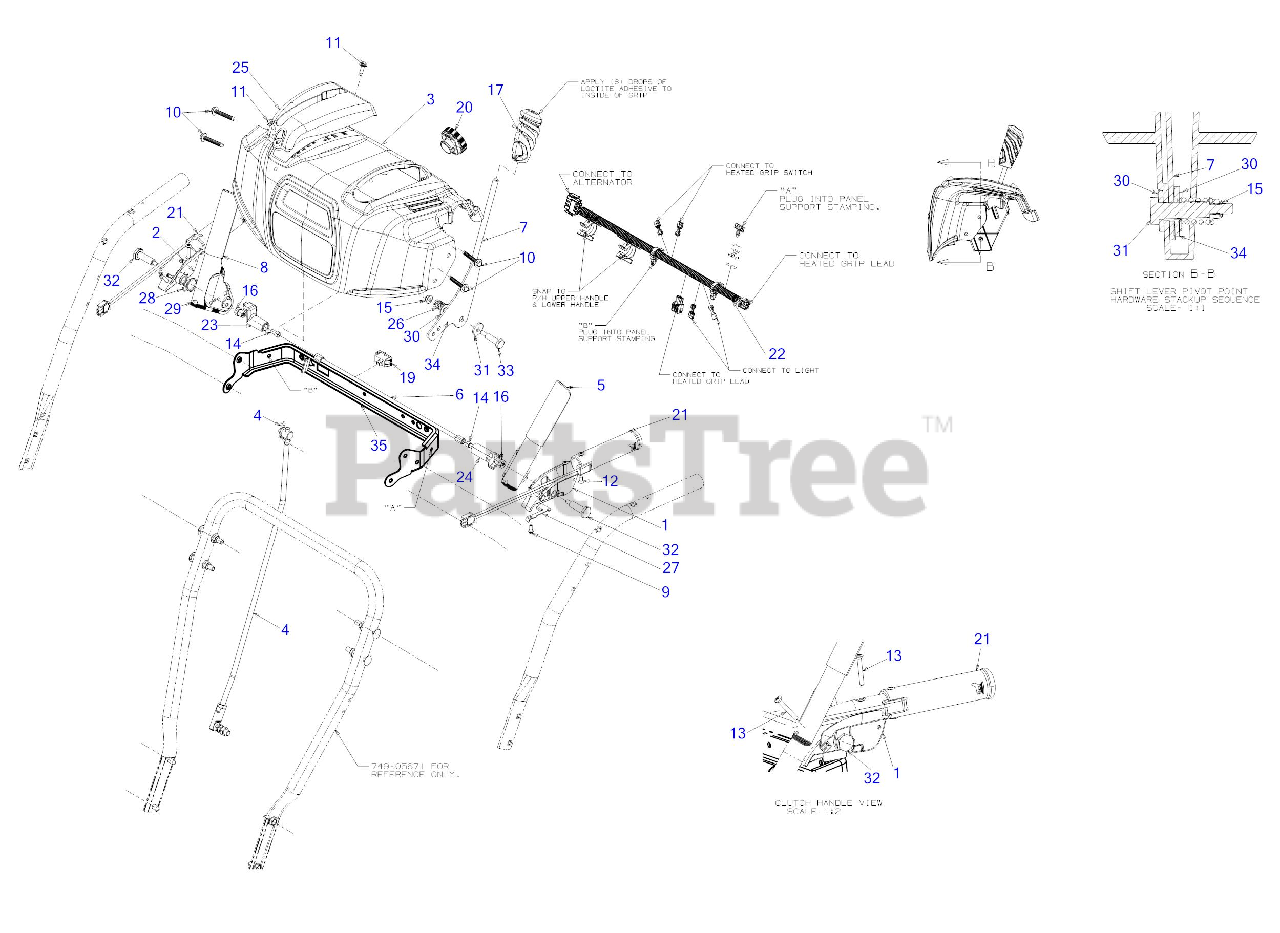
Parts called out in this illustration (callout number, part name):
1	CLUTCH LOCK HANDLE ASSEMBLY (LH)
2	CLUTCH LOCK HANDLE ASSEMBLY (RH)
3	HANDLE PANEL ASSEMBLY
4	SHIFT ROD ASSEMBLY
5	HANDLE ASSEMBLY (LH)
8	HANDLE ASSEMBLY (RH)
9	SCREW #8-16 x .50
10	SCREW 1/4-20 x 1.625
11	SCREW 1/4-10 x .750
12	SCREW #10-16 x .625
13	SCREW #10-24 x 1.375
14	SCREW 1/4-20 x .50
15	FLANGE LOCK NUT
16	HEX NUT W/PATCH
17	PTO HANDLE GRIP .355 ID
19	HEATED GRIP SWITCH
20	HEADLIGHT ASSEMBLY
22	HEATED GRIPS HARNESS
24	CLUTCH LOCK CAM
25	HANDLE PANEL COVER
26	COMPRESSION SPRING
27	CLUTCH SPRING
28	TORSION SPRING
29	RUBBER BUMPER
30	FLAT WASHER
32	SHOULDER SCREW .437 x 1.345 1/4-20
33	SHOULDER SCREW
34	FRICTION WASHER
35	HANDLE SUPPORT BRACKET
